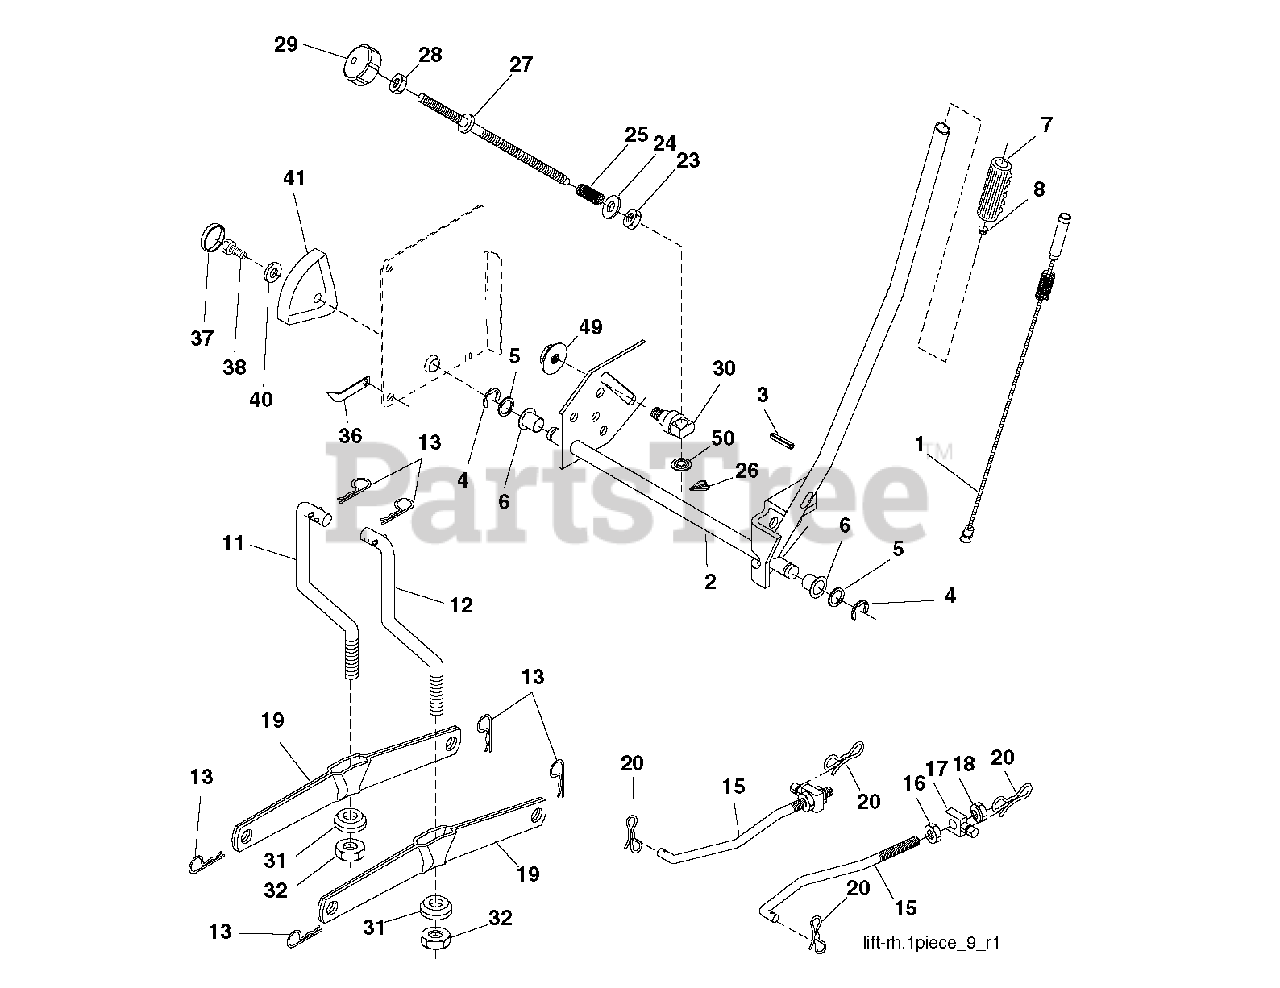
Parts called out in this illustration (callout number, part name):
1	PLUNGER.ASM.LIFT.LVR.BLK.17.32
2	SHAFT ASM R HANDLE
3	PIN GROOVE
4	RETAINING RING LT
6	BEARING.NYLON
7	GRIP HANDLE
8	PLUNGER BUT KIT
11	LINK
12	LINK
13	RETAINER-SPRNG RB
15	LINK.SUSPENSION.FRONT
16	NUT
18	NUT
19	ARM.REAR.SUSPENSION
20	PIN.COTTER.7/16.BOW TI
25	SPRING**
26	RETAINER CLIP
27	ROD ADJ LIFT
28	NUT
29	KNOB INF 3/8-16
31	BEARING.PIVOT.LIFT
32	NUT CROWNLOCK 3/8-24
36	POINTER, HEIGHT INDICATOR
37	PLUG,HOLE
38	SCREW 5/16-18X1
41	HEIGHT INDICATOR
49	NUT
50	NUT PUSH M
